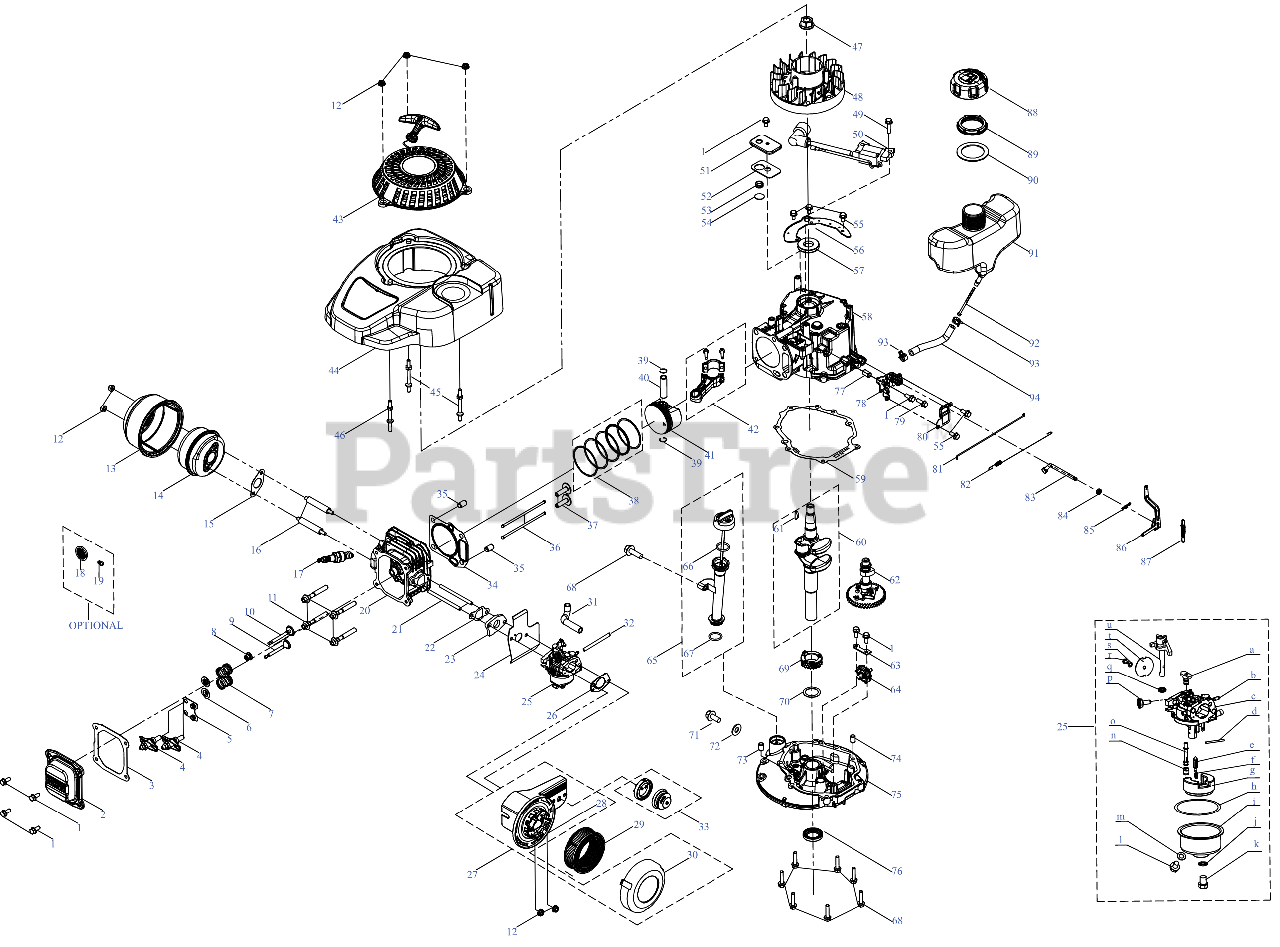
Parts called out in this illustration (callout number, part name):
1	BOLT M6-1 x 14 GR8.8
2	VALVE COVER
3	VALVE COVER GASKET
4	ROCKER ARM ASSEMBLY
5	PUSH ROD GUIDE
6	VALVE SPRING RETAINER
7	VALVE SPRING
8	INTAKE VALVE SEAL
9	EXHAUST VALVE
10	INTAKE VALVE
11	SCREW M8 x 54 GR10
13	MUFFLER SHIELD
14	MUFFLER ASSEMBLY
15	MUFFLER GASKET
16	STUD M6-1 x 76
17	SPARK PLUG
18	SPARK ARRESTOR
19	SCREW M3.5 x 9.5
20	CYLINDER HEAD
21	STUD M6 x 98
22	CARBURETOR INSULATOR GASKET
23	CARBURETOR INSULATOR
24	CARBURETOR GASKET
25	CARBURETOR ASSEMBLY
26	AIR FILTER BASE GASKET
27	AIR FILTER ASSEMBLY
28	AIR FILTER BASE
29	PAPER AIR FILTER
30	AIR FILTER COVER
31	BREATHER HOSE
32	PRIMER HOSE
33	VENTED PRIMER ASSEMBLY
34	CYLINDER HEAD GASKET
36	PUSH ROD
37	TAPPET (LIFTER)
38	PISTON RING SET
39	SNAP RING-PISTON PIN
40	PISTON PIN
41	PISTON
42	CONNECTING ROD ASSEMBLY
43	STARTER RECOIL ASSEMBLY
44	ENGINE SHROUD ASSEMBLY
45	STUD M6 x 75
46	STUD M6 x 73
47	FLYWHEEL NUT
48	FLYWHEEL
49	BOLT M6-1 x 25 GR8.8
50	IGNITION COIL
51	BREATHER COVER PLATE
52	BREATHER COVER GASKET
53	BREATHER VALVE SPRING
54	BREATHER VALVE
55	BOLT M6-1 x 10 GR8.8
56	COVER SHIELD PLATE
57	UPPER CRANKSHAFT SEAL
59	CRANKCASE COVER GASKET
60	CRANKSHAFT
61	FLYWHEEL KEY
62	CAMSHAFT ASSEMBLY
63	GOVERNOR GEAR MOUNTING PLATE
64	GOVERNOR GEAR/SHAFT ASSEMBLY
66	O-RING
68	BOLT-M6-1 x 28 GR8.8
69	CRANKSHAFT TIMING GEAR
70	THRUST WASHER
71	OIL DRAIN PLUG
72	WASHER
73	DOWEL PIN
74	DOWEL PIN
75	CRANKCASE COVER
76	LOWER CRANKSHAFT SEAL
77	Control Bracket Spacer
78	VARIABLE SPEED BRACKET
79	BOLT M6-1 x 35 GR8.8
80	VARIABLE SPEED CONTROL COVER
81	THROTTLE LINKAGE
82	THROTTLE LINKAGE SPRING
83	GOVERNOR ARM SHAFT
84	GOVERNOR SEAL
85	COTTER PIN
86	GOVERNOR ARM ASSEMBLY
87	GOVERNOR SPRING
88	FUEL CAP ASSEMBLY
89	FUEL TANK NUT
90	FUEL TANK UPPER GROMMET
92	FUEL FILTER
93	HOSE CLAMP
94	FUEL HOSE
